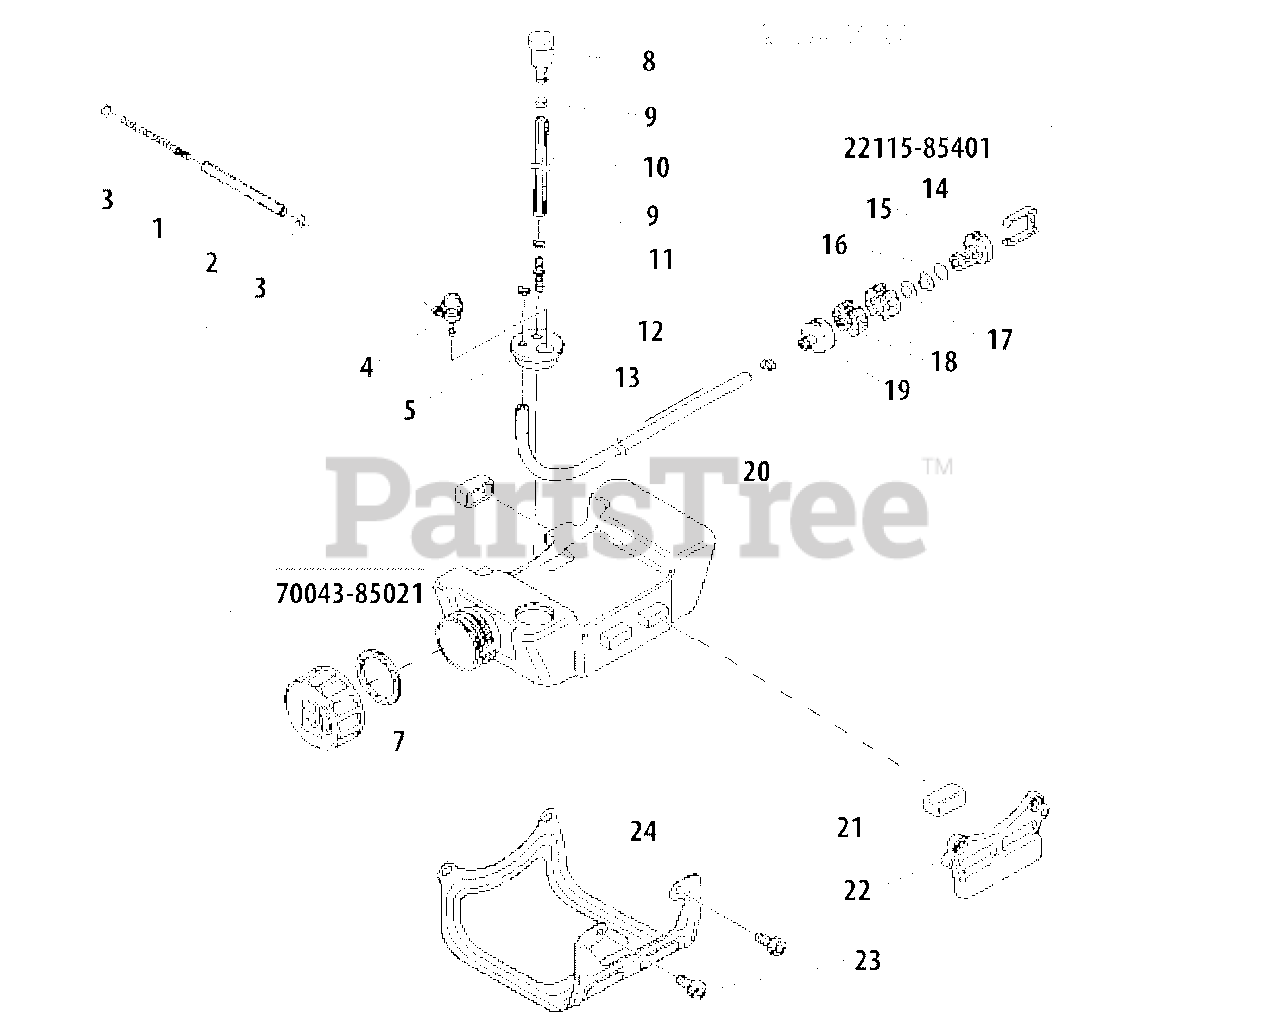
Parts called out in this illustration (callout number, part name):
1	SPRING
2	PIPE
3	CLIP Ø6
4	BULB, PURGE
5	GROMMET
7	GASKET, FUEL CAP
8	VENT ASSY
9	CLIP Ø6
10	PIPE, FUEL
11	CONNECTOR, PIPE
12	CLIP Ø6
13	PIPE, FUEL
14	CLIP, FILTER
15	BODY, FUEL FILTER
16	RING, RETAINING
17	SCREEN
18	FILTER, FUEL
19	WEIGHT, FUEL LINE
20	CLIP Ø6
21	CUSHION, FUEL TANK
22	BRACKET, FUEL TANK
23	BOLT M5×12
24	GUARD, METAL FUEL TANK
A	FUEL TANK ASSY
A	CAP ASSY, FUEL
A	FILTER, FUEL
